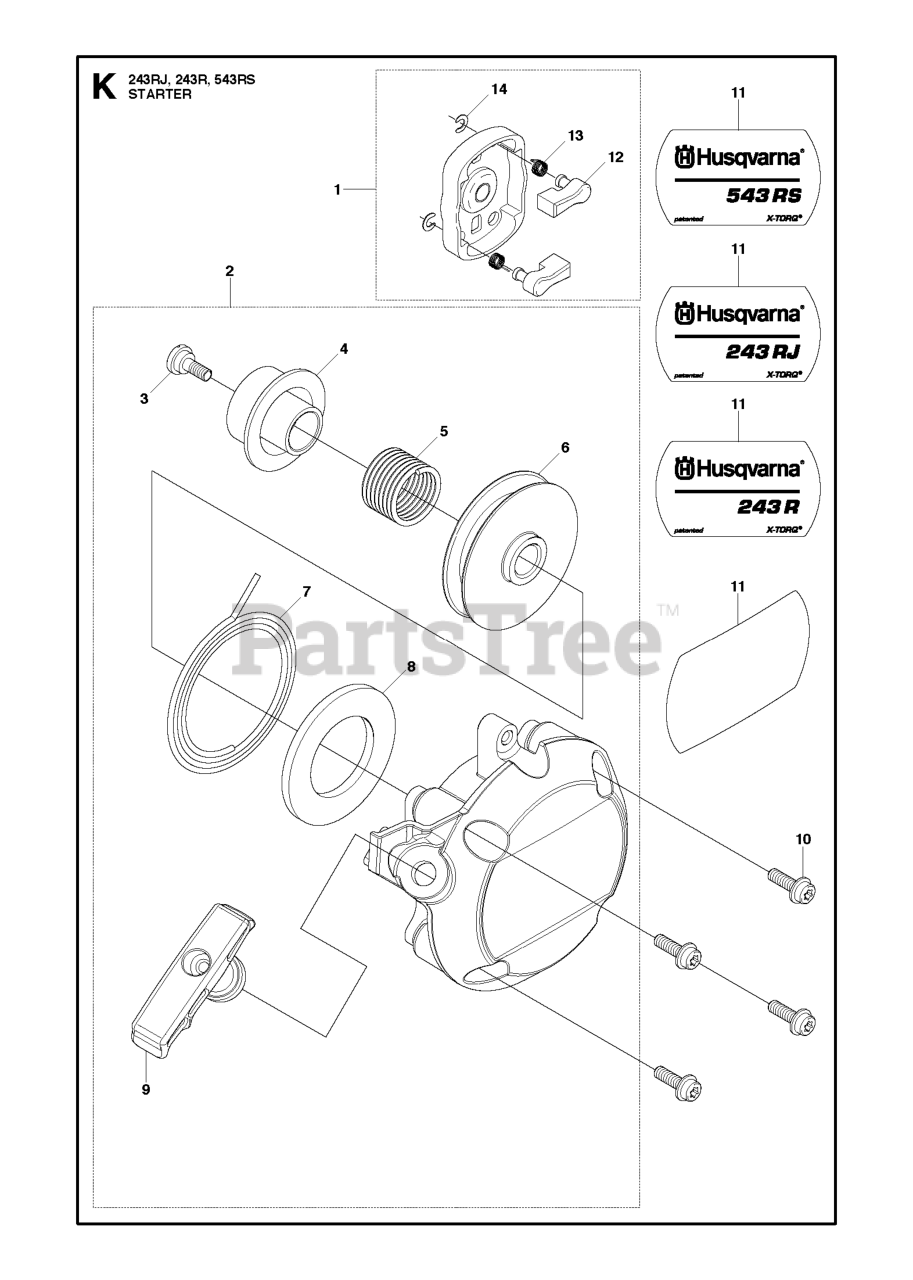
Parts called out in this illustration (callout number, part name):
1	PULLEY ASSY
4	PLATE, CAM
5	SPRING, DAMPER
8	SPRING,SPIRAL
11	LABEL,RECOIL
11	DECAL RECOIL GZ40N7
11	DECAL RECOIL
